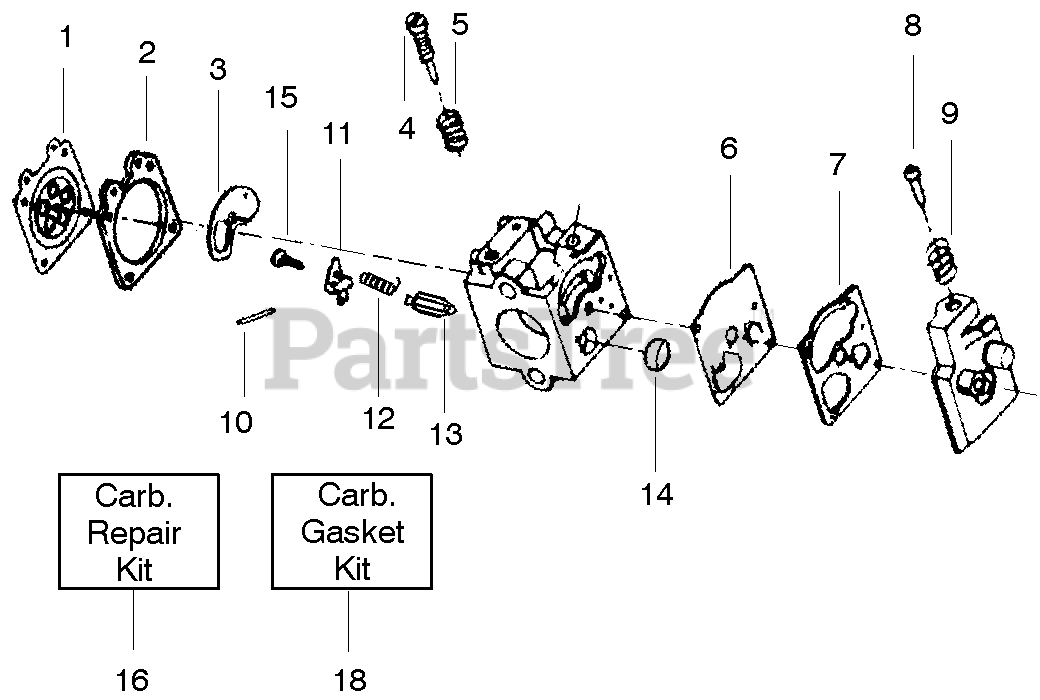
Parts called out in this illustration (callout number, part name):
1	Metering Diaphram
2	Metering Diaphragm Gasket
3	Circuit Plate Gasket
4	Mixture Needle
5	Mixture Needle Spring
6	Fuel Pump Diaphragm
7	Fuel Pump Gasket
8	Idle Speed Screw
9	Idle Speed Spring
10	Metering Lever Pin
11	Metering Lever
12	Metering Lever Spring
13	Inlet Needle Valve
14	Fuel Inlet Screen
15	Metering Lever Pin Screw
16	Carb. Kwik Repair Kit
17	Carb. Gasket/Diaphragm Kit (+Indicates Contents)
